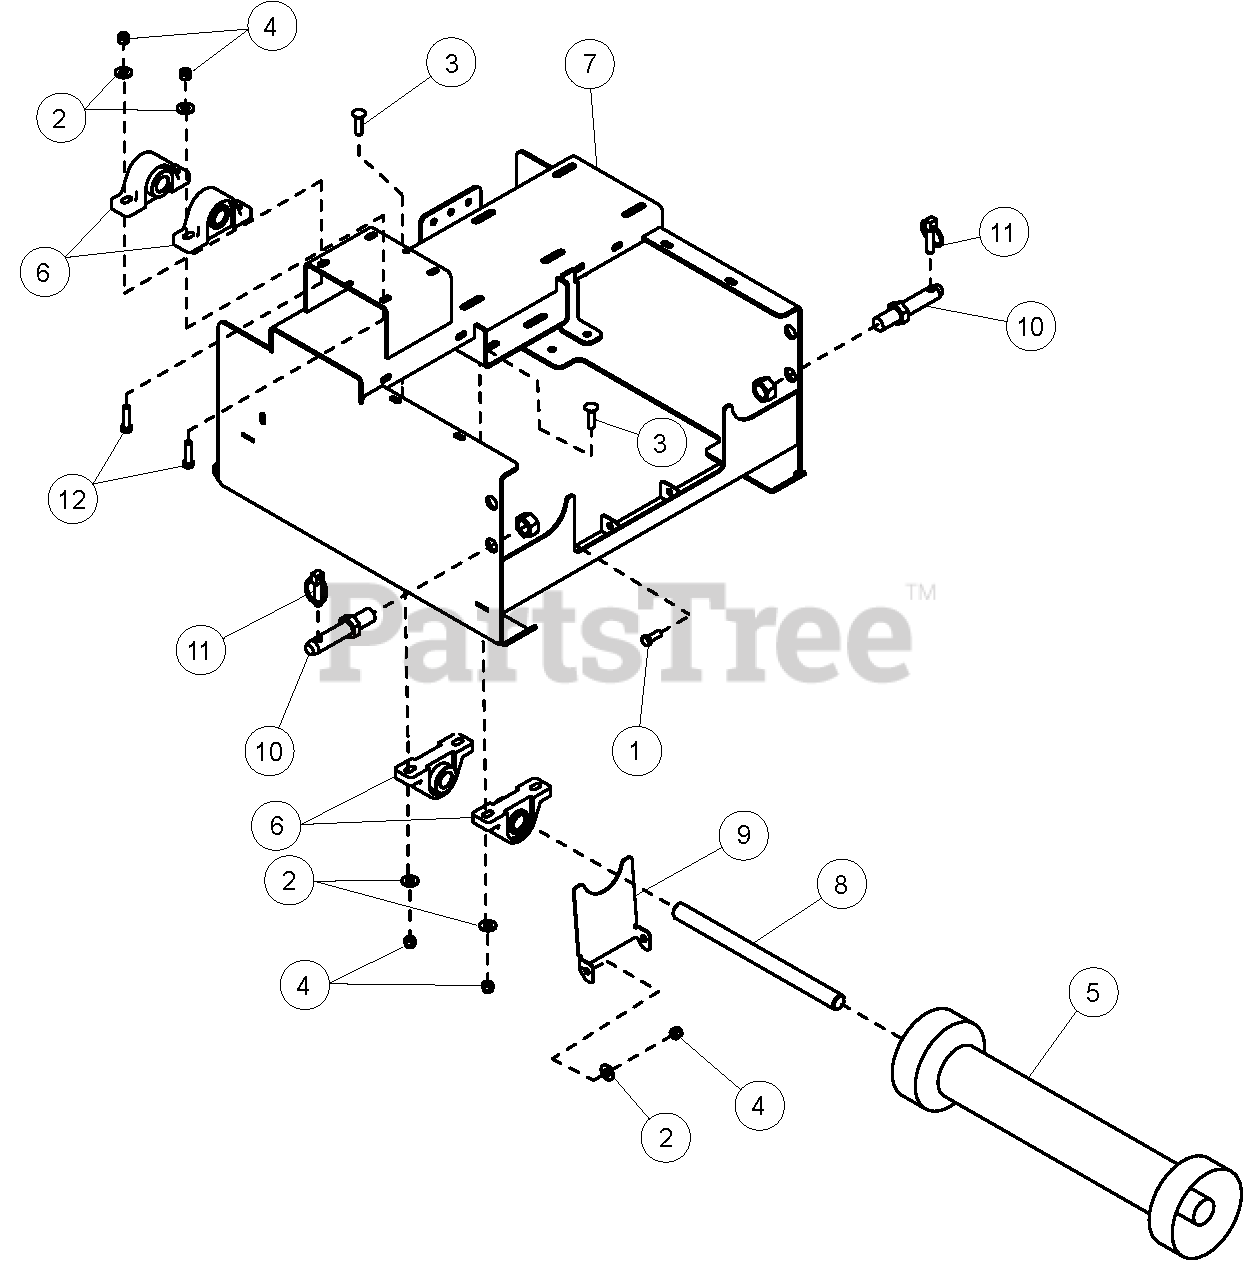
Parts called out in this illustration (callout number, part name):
1	BOLT, 3/8 NC X 1" GR5 CAPSCREW ZP
2	WASHER, 3/8" FLAT
3	BOLT, 3/8 X 1-1/2" CRG
4	NUT, 3/8" NYLOCK
5	SHAFT, CHIPPER DRIVE (SUPERSEDED BY 36407-00)
5	DRIVESHAFT, 540 C/S WS
6	PILLOW BLOCK BEARING 1 IN
7	WELDMENT, CHIPPER 3 PT.
8	JACKSHAFT, CHIPPER
9	PLATE, PTO HOLDER
10	PIN, LIFT ARM 7/8 X 5" LG
11	PIN, 7/16 X 1-3/4" LYNCH
12	BOLT, 3/8 X 1-1/2" GR5 HCS ZP
